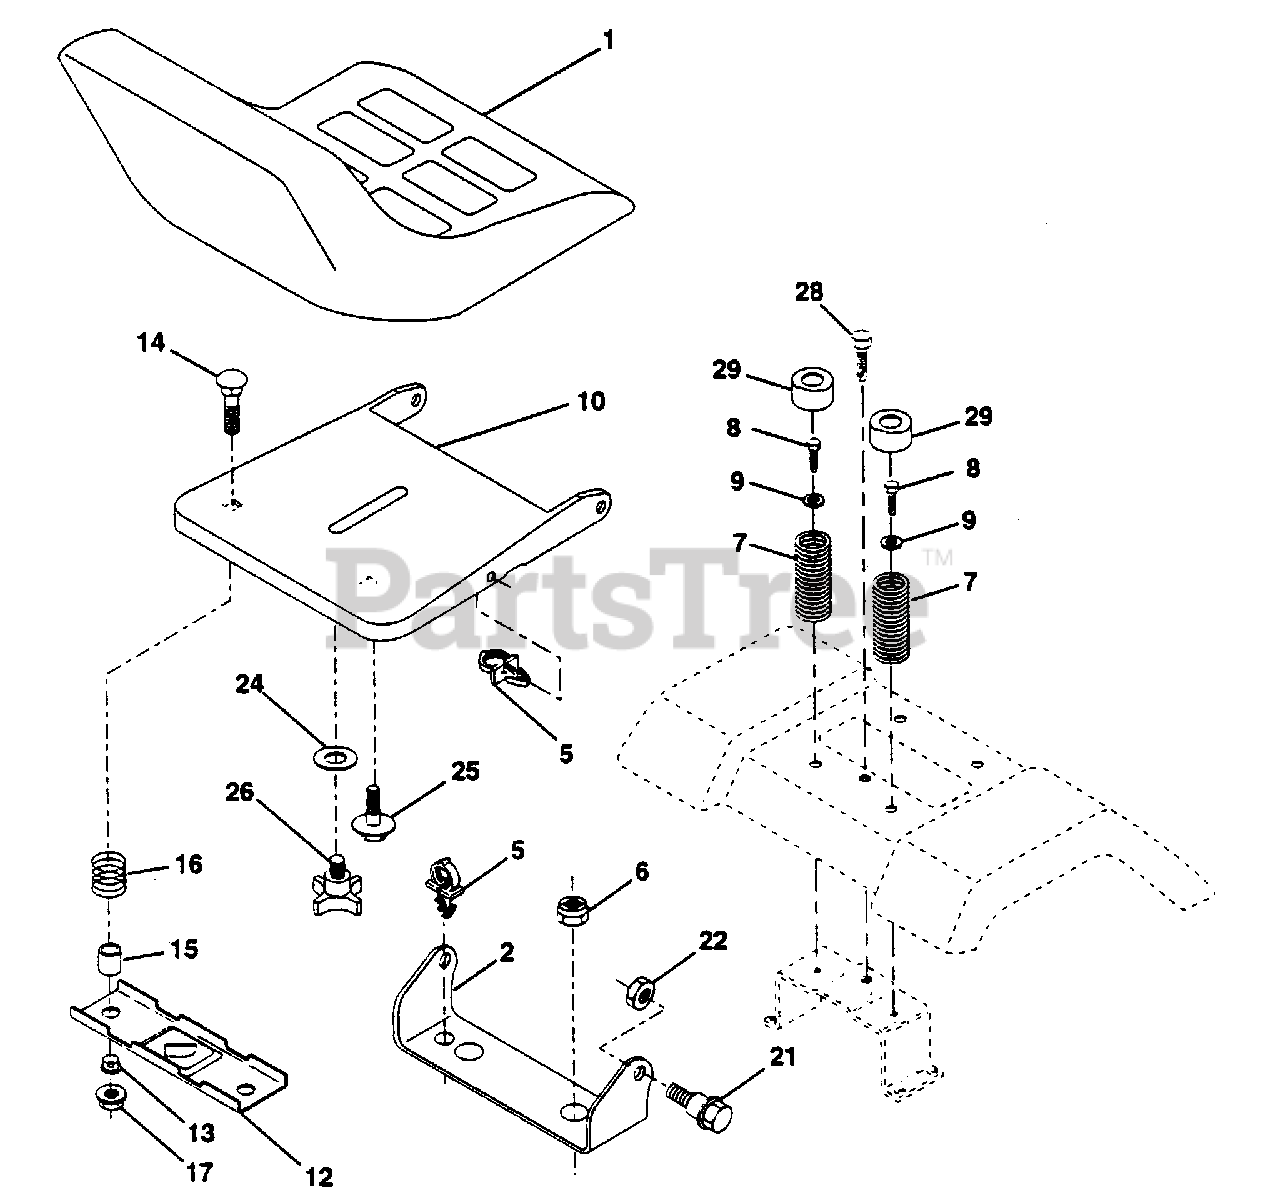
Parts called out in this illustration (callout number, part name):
1	Seat V-560 Gry/blk Std (AYP part number)
2	Bracket Pivot Seat (AYP part number)
5	Clip, Push-In (AYP part number)
6	Nut Lock Hex w/Wsh 3/8-16 Unc (AYP part number)
7	Spring Seat Cprsn 2 250 Blk Zi (AYP part number)
8	Screw Hwsh Thdrol 5/16-18 x 1/2 (AYP part number)
9	Washer 13/32 X 1 X 14 Ga (AYP part number)
10	Pan Seat (AYP part number)
12	Bracket Mounting Switch (AYP part number)
13	Bushing Snap Blk Nyl 50 Id (AYP part number)
14	Bolt Rdhd Sht Nk 1/4-20x1-3/8
15	Spacer Split 28x 88 Yel Zinc (AYP part number)
16	Spring Cprsn 1 310 Blk Pnt (AYP part number)
17	Nut Lock 1/4 Lge Flg Gr 5 Zinc (AYP part number)
21	Bolt Shoulder 5/16-18 Unc Blkz (AYP part number)
22	Nut Crown Lock 5/16-18
24	Washer 17/32 X 1-3/16 X 12 Ga (AYP part number)
25	Bolt Shoulder 5/16-18 X 62 (AYP part number)
26	Knob Seat 1/2-13unc Blk (AYP part number)
28	Screw Thdrol 3/8-36 x 1/2 (AYP part number)
29	Cap Spring Seat (AYP part number)
